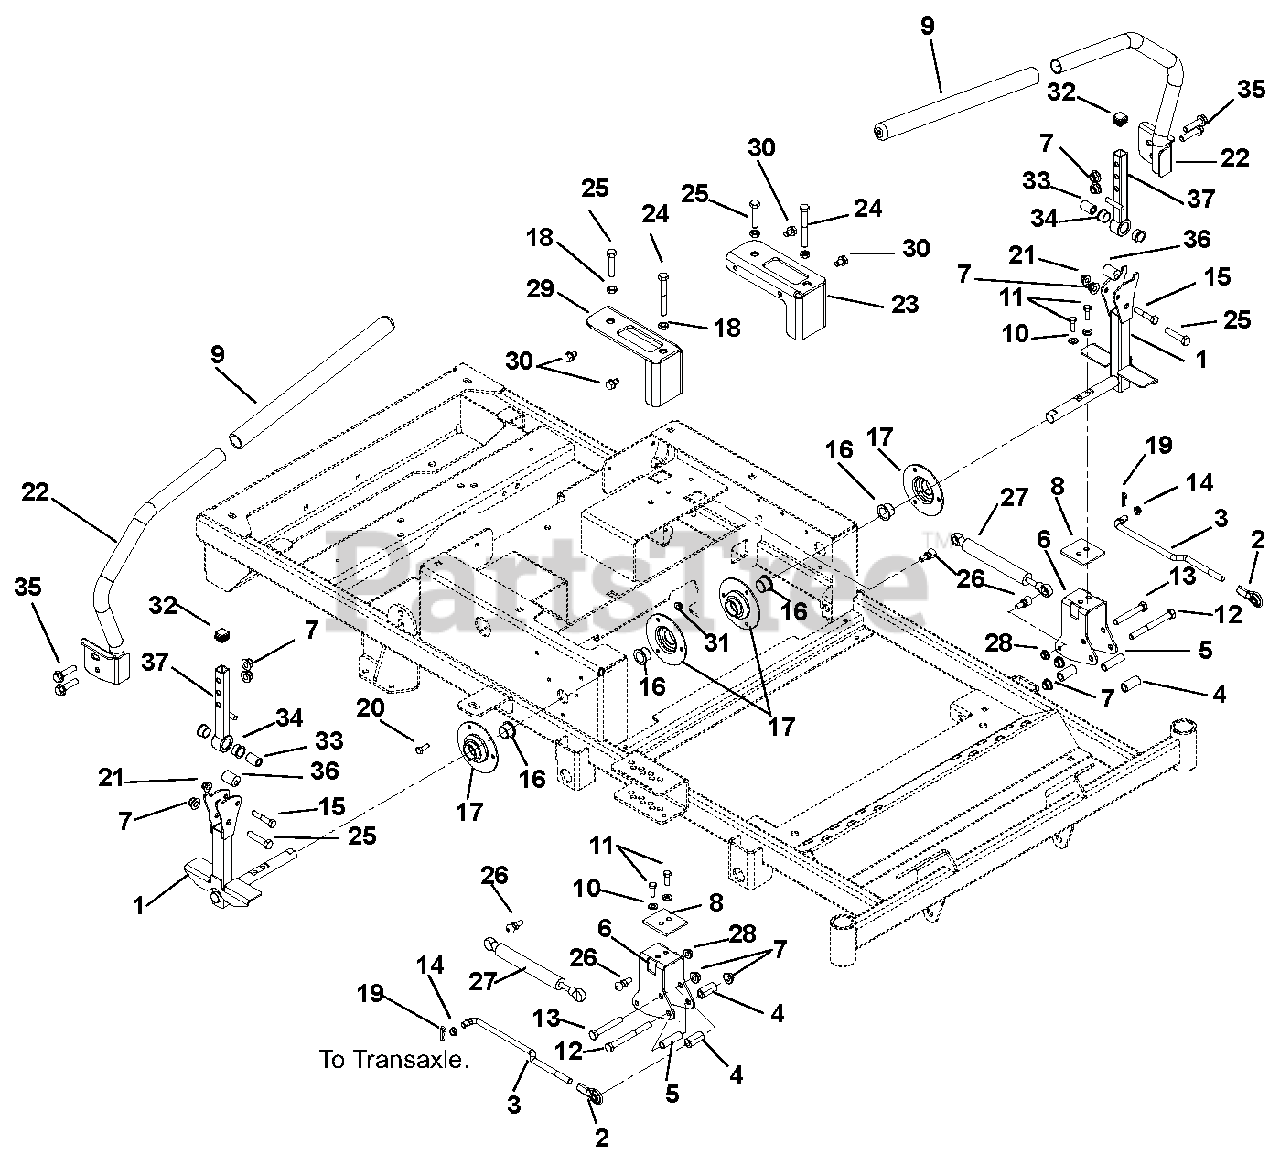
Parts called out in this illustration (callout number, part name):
1	WMT, CONTROL ARM
2	ROD END, .38 RH
3	LINK, TRANSMISSION
4	BSHG, SPCR .390X.625X1.25 PM
5	SPACER, STEERING
6	BRKT, STEERING
7	@NUT-LK-NYL-FLG .38-16 YWZC
8	PLATE, STEERING REINFORCING
9	GRIP, HANDLEBAR 15" FOAM
10	@WSHR-LK .31X.078 REG YWZC
11	BLT-HEX .31-18X1.00 GR8 YWZC
12	@BLT-HEX .38-16X3.75 GR5 YWZC
13	@BLT-HEX .38-16X2.50 GR5 YWZC
14	BUSHING, POLYLINER-.38 SNAPIN
15	@BLT-HEX .31-18X1.75 GR5 YWZC
16	BSHG-FLG .750X1.000X.625X1.250
17	BEARING FLANGE
18	NUT-HEX-JAM .375-16 YWZC
19	PIN-HAIR INT .08X.18X1.18 YWZC
20	@BLT-HEX .25-20X.75 GR5 YWZC
21	@NUT-LK-NYL-FLG .31-18 YWZC
22	WMT, STEERING HANDLE RH
23	BRACKET, LH SPEED CONTROL
24	BLT-HEX .38-16X3.00 GR5 FTH YZ
25	BLT-HEX .375-16X1.750 FTD YWZC
26	STUD- BALL
27	DAMPER, CONTROL
28	@NUT-LK-TOP-FLG .31-18 YWZC
29	BRACKET, RH SPEED CONTROL
30	@SCR-TAP .31-18X.50 HWH TR YWZ
31	@NUT-LK-TOP-FLG .25-20 YWZC
32	CAP PLUG, SQ 3/4-14-20 RIBBED
33	SPACER, .375X.625X.970 (PM)
34	BSHG-FLG, .625X.75X.450X.875
35	BOLT, SERRATED HEAD .38-16X1.5
36	BSHG, ECCENTRIC .328X.750X.970
37	WMT, UPPER CONTROL ARM
